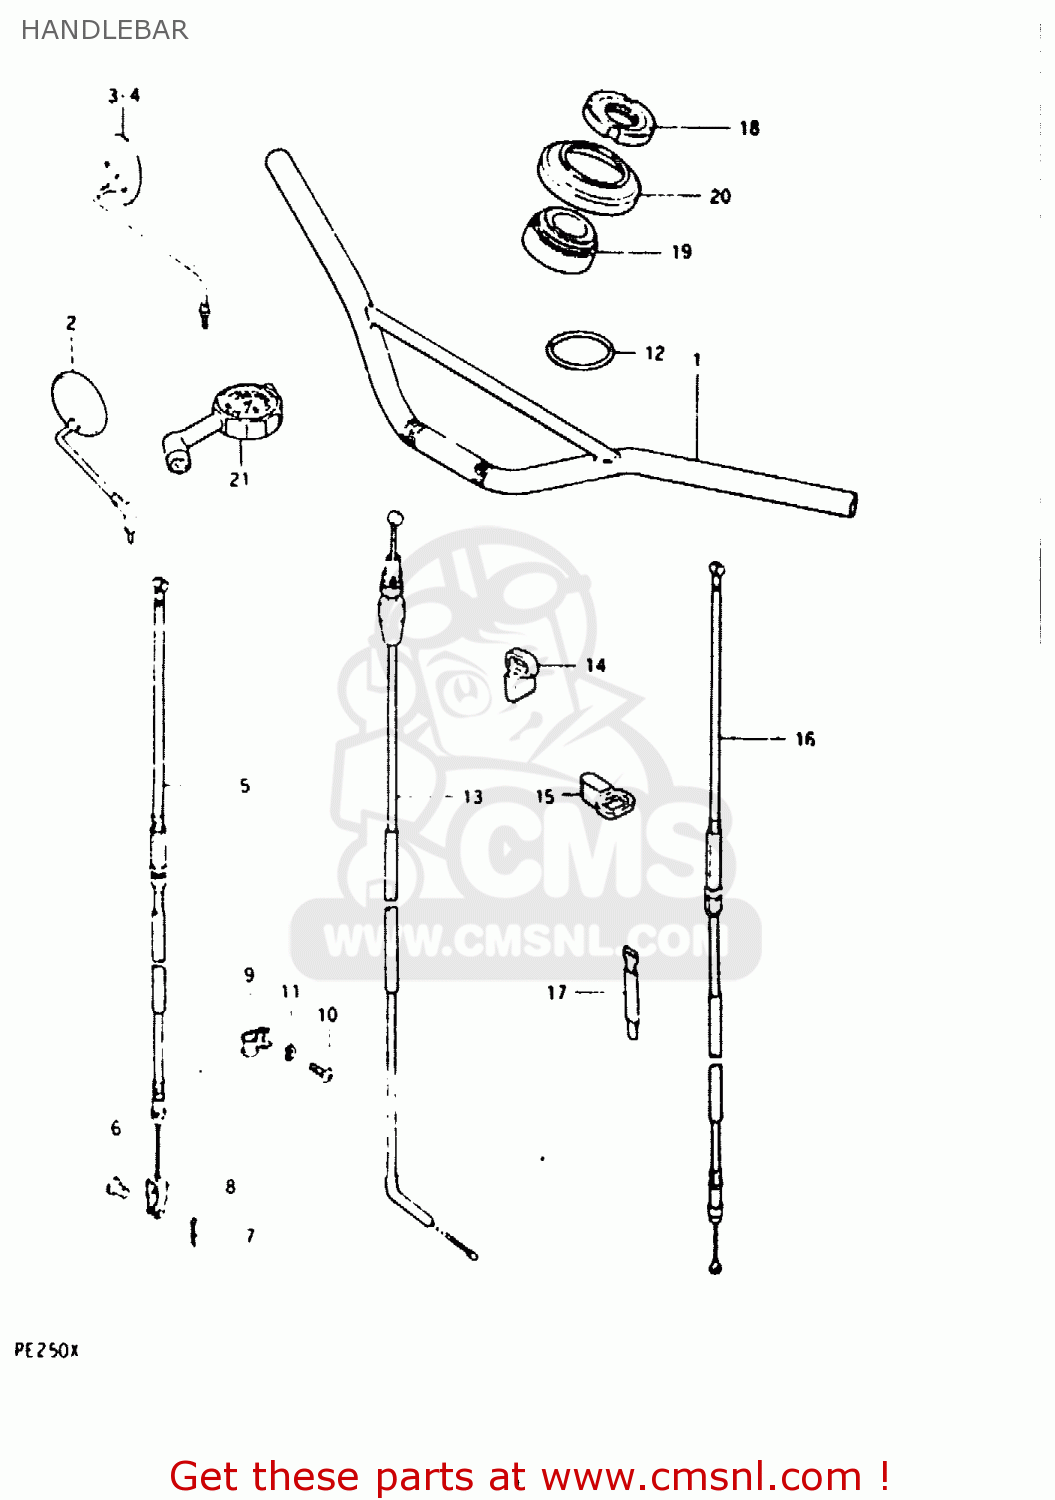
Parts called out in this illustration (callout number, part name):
1	HANDLEBAR
5	CABLE,FRONT BRAKE
6	PIN(L:13.5)
7	PIN
8	BRAKE CABLE HOOK
9	GUIDE,CABLE
10	SCREW
11	LOCK WASHER
12	O RING(D:3.53,ID:69.44)
13	CABLE ASSEMBLY,THROTTLE
14	GUIDE,CABLE
15	GUIDE,CLUTCH CABLE
16	CABLE,CLUTCH
17	CLAMP
18	NUT,STEERING STEM(25X44X10)
19	TAPER,ROLLER BEARING
20	DUST SEAL,STEERING,UPPER
21	GAUGE ASSY,AIR PRESSURE
